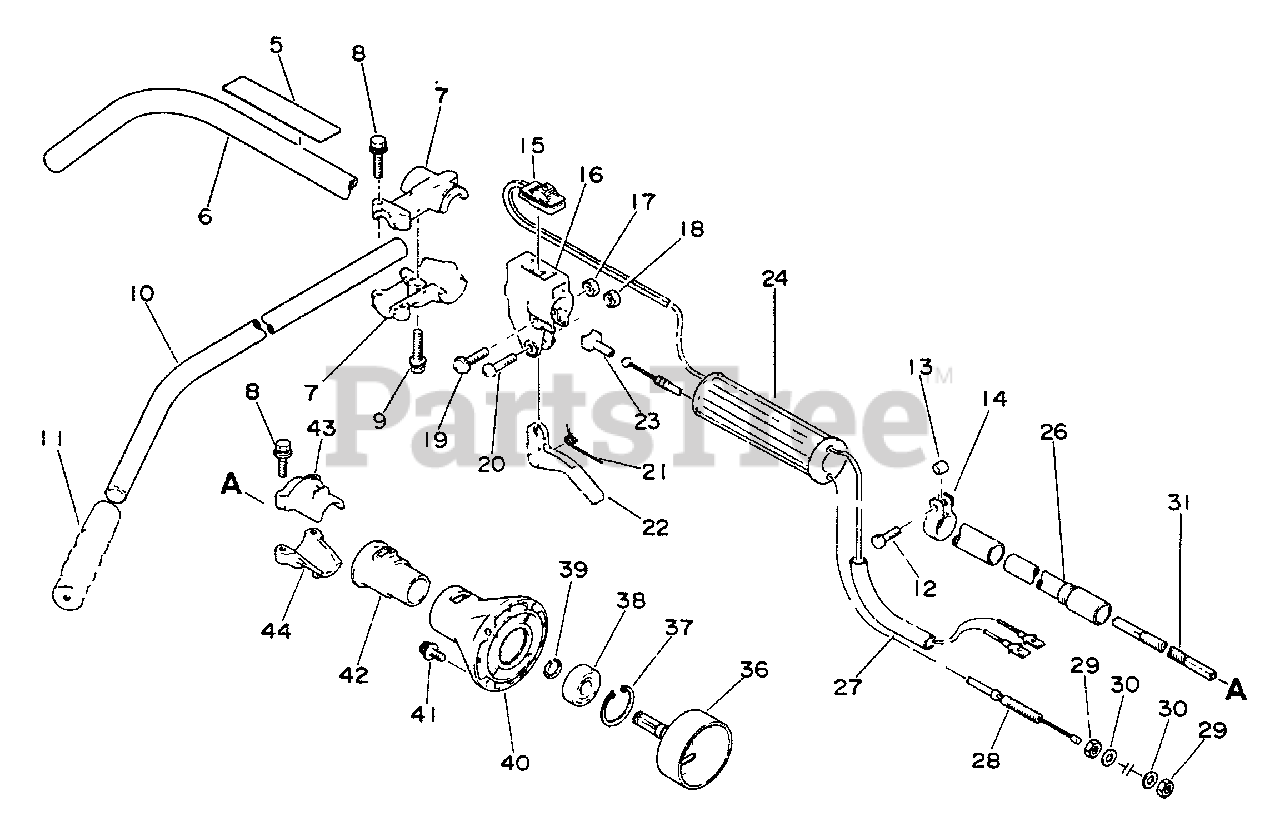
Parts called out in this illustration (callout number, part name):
5	LABEL - CAUTION
6	PIPE, MAIN
7	BRACKET, HANDLE
8	BOLT - 5X25
9	BOLT - 5X28
10	HANDLE
11	GRIP, HANDLE
12	BOLT - 5X18
14	CLAMP
15	IGNITION SWITCH ASSY
16	BRACKET, THROTTLE
18	LOCKNUT - 5
19	SCREW - 5X28
20	SCREW - 5X30
21	SPRING, TRIGGER
22	TRIGGER, THROTTLE
23	GUIDE, CABLE
24	GRIP, HANDLE
26	LINER
27	TUBE - VINYL
28	CABLE, THROTTLE
30	WASHER - 6
31	DRIVESHAFT - FLEXIBLE
36	DRUM, CLUTCH
37	RING, RETAINING - 32
38	BEARING, BALL - 6201
39	RING, RETAINING - 12
40	FLANGE, DRIVESHAFT
41	SCREW - 5X16
42	CUSHION
43	CLAMP, MAIN PIPE
44	Holder, housing
